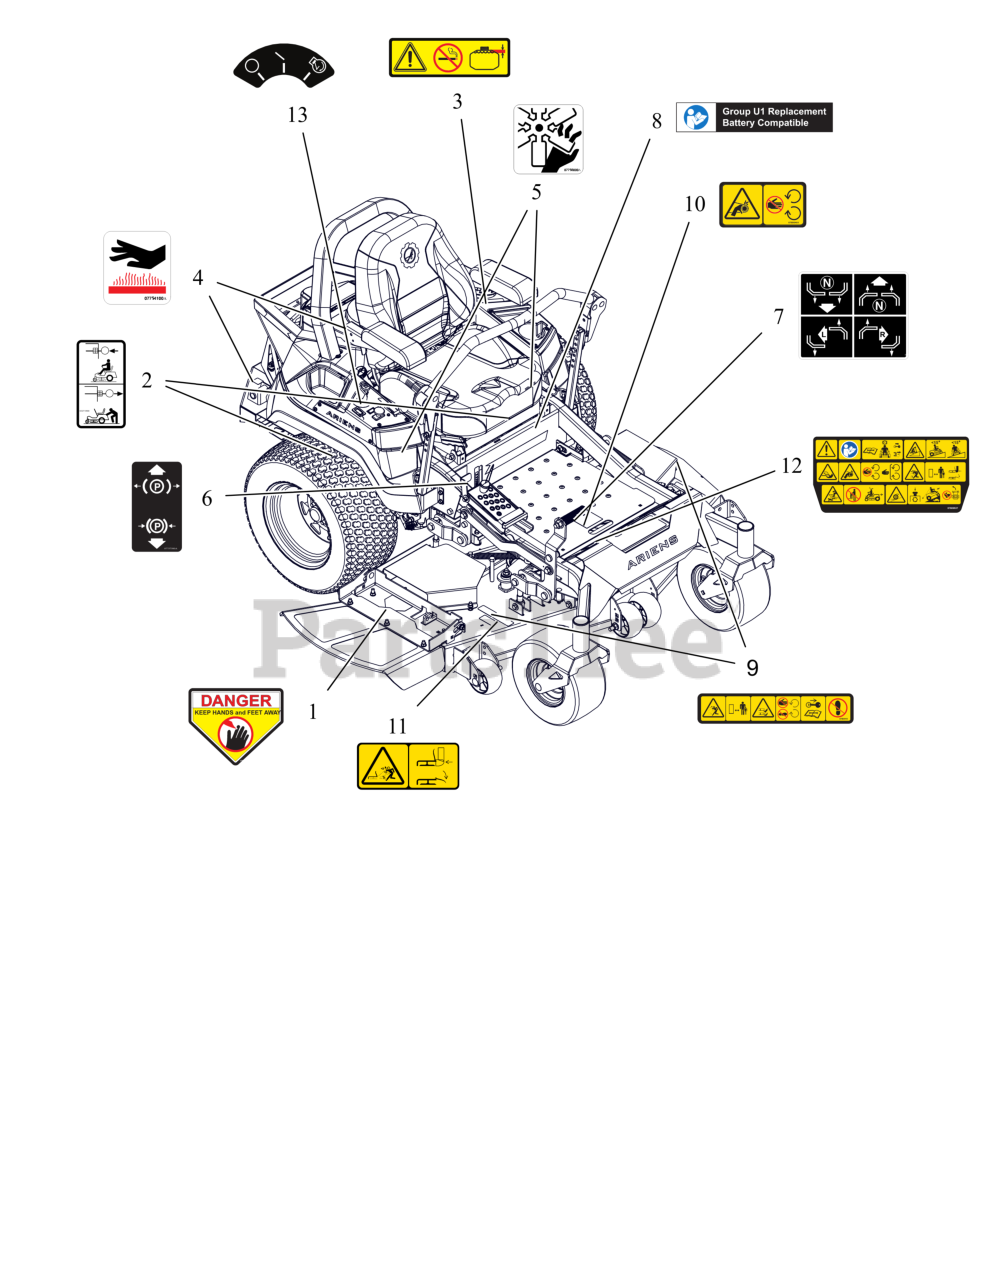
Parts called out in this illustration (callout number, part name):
1	DECAL, DANGER
2	DECAL, TRANSMISSION DISCONNECT
3	DECAL, FUEL WARNING
4	DECAL, HOT SURFACE
5	DECAL, DANGER FAN
6	DECAL, PARKING BRAKE LEVER
7	DECAL, INSTRUCTIONAL-STEERING
8	DECAL, U1 BATTERY REPLACEMENT
9	DECAL, DECK SAFETY
10	DECAL, SAFETY - GUARDING
11	DECAL, SAFETY - DECK GUARDING
12	DECAL, MAIN SAFETY
13	DECAL, KEYSWITCH
